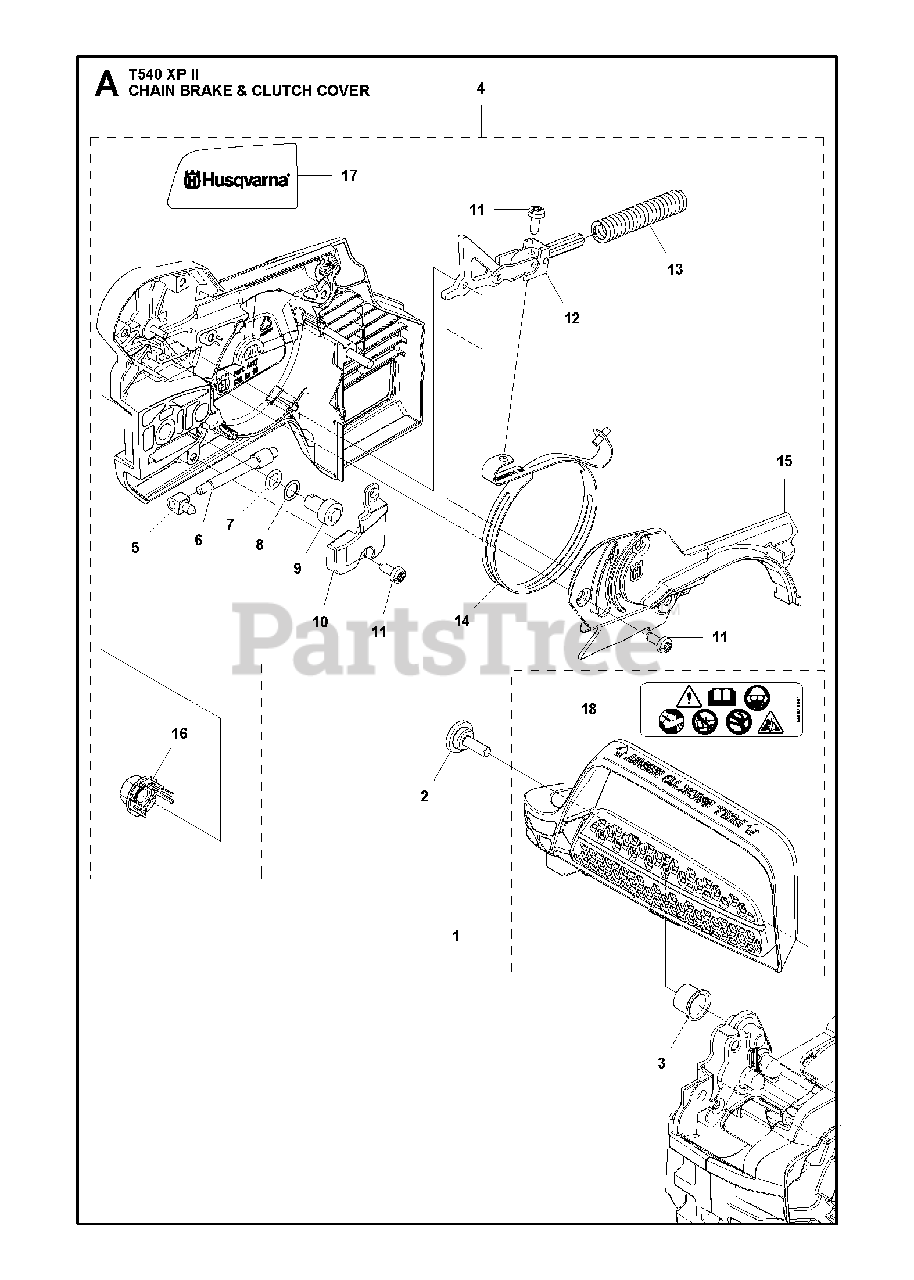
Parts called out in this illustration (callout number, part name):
1	HAND GUARD ASSY
4	CLUTCH COVER ASSY
5	PAWL
6	SCREW
7	O-RING
8	WASHER
9	WORM WHEEL
10	COVER LID
11	SCREW CITXPANT
12	KNEE JOINT ASSY
13	BRAKE SPRING
14	BRAKE BAND ASSY
15	COVER BRAKE COVER
16	NUT RETAINER ASSY
17	DECAL
18	DECAL
